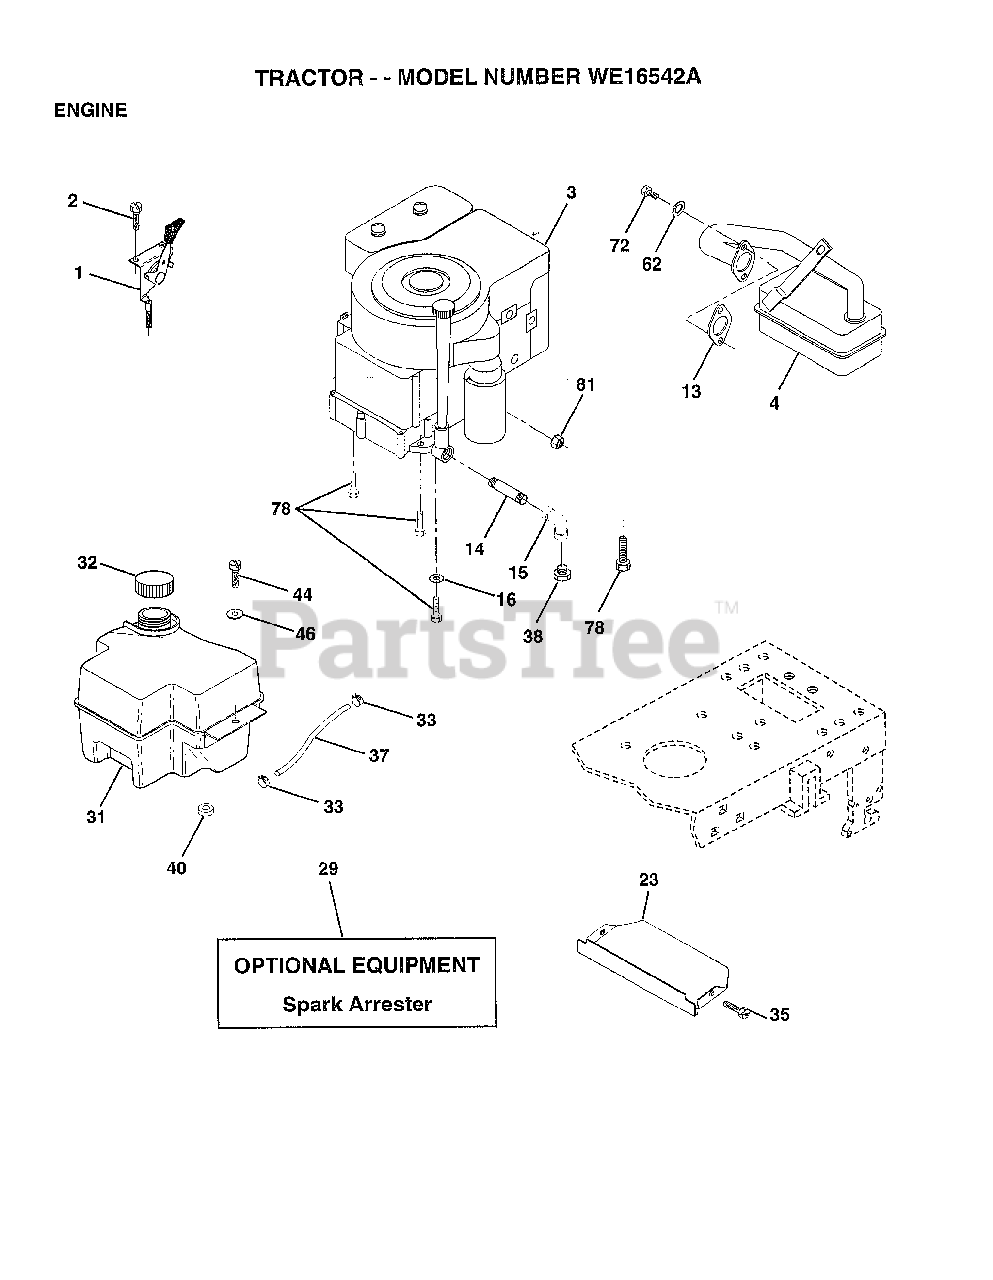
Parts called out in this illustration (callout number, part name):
1	CONTROL THROTTLE
2	SCREW LT
4	MUFFLER
13	GASKET ENG 1 313 LD TIN PLATED
14	PIPE NIPPLE
15	ELBOW
16	LOCKWASHER
23	SHIELD.BRN/DBR.GD
31	TANK.FUEL.FRONT.
32	CAP ASM FUEL
33	HOSE CLAMP
35	SCREW
37	LINE FUEL
44	SCREW HEX CRT
46	WASHER
62	LOCKWASHER
72	SCREW
78	SCREW
81	NUT
